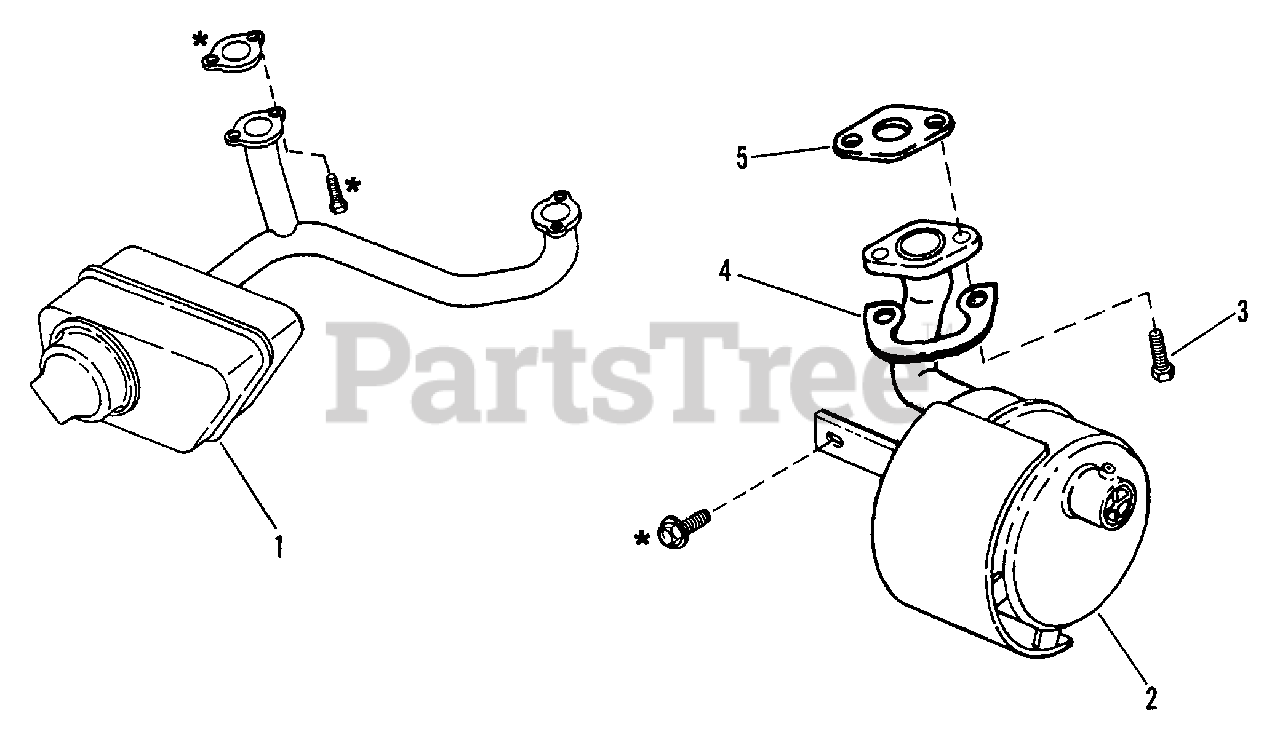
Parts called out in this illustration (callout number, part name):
1	MUFFLER (16HP Briggs Engine)
2	MUFFLER (16 HP Tecumseh Engine)
3	SCREW, Hex Head 5/16-18 x 1" Grade 5
4	PLATE, Lock
5	GASKET, Exhaust
